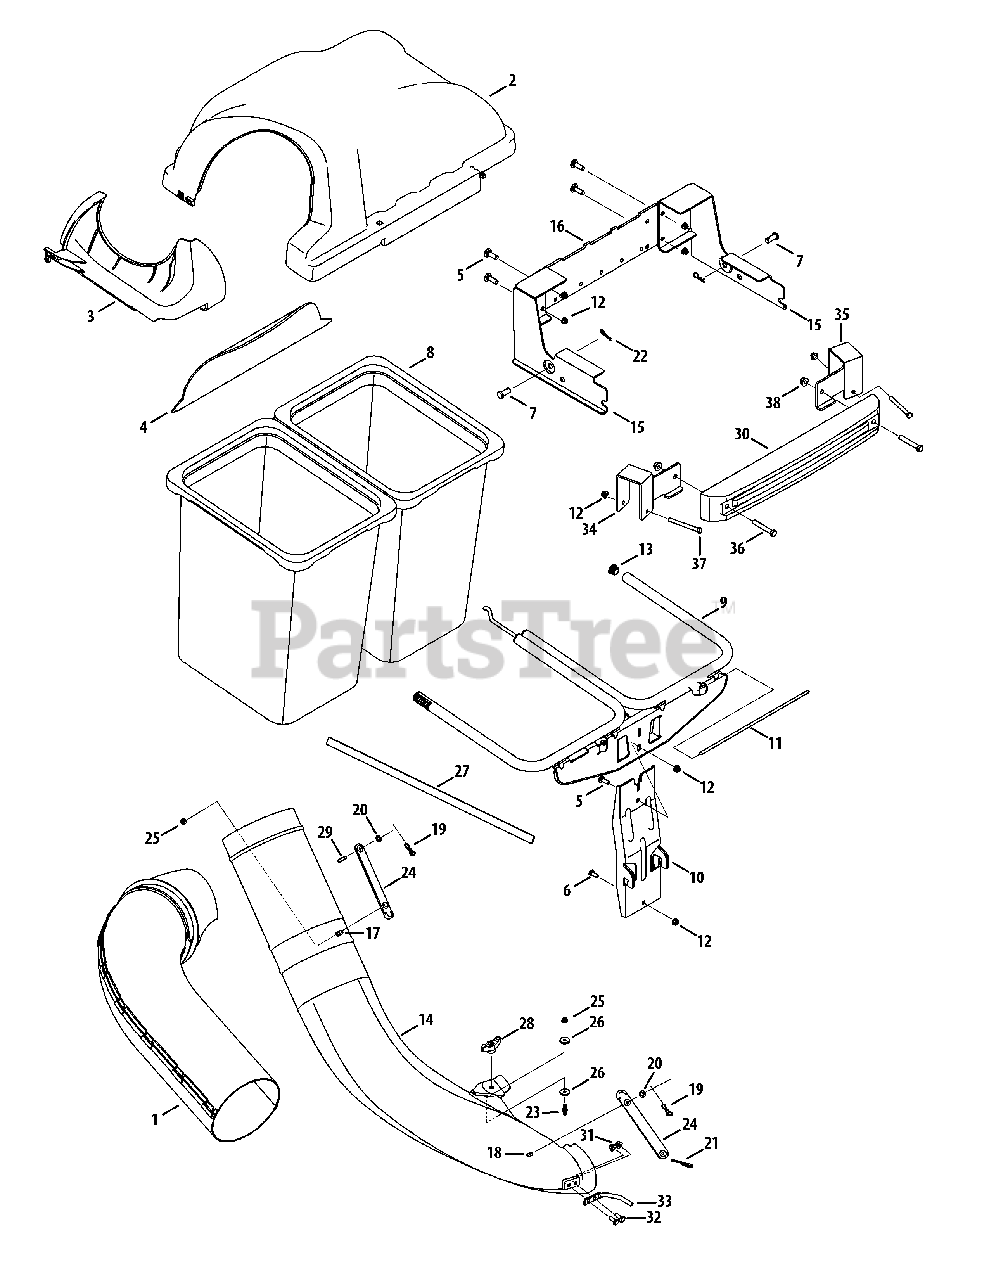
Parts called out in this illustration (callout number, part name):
1	Upper Chute Assembly
2	Twin Bagger Cover Assembly
3	Upper Chute Support
4	Bagger Cover Screen
5	Carriage Screw, 5/16-18 x 1.00"
6	Hex Head Screw, 5/16-18 x 1.00"
7	Clevis Pin, .50" Dia. x 1.18
8	Grass-bag Assembly
9	Twin Bag Support Assembly
10	Vertical Support Bracket
11	Cover Hinge Pin
12	Flange Lock Nut, 5/16-18
14	Chute, Lower
15	RZT Hitch Bracket Kit
16	Universal Cross Bracket
17	Grass-catcher Pin
18	Clevis Pin 5/16 x 3/4
19	Bow-Tie Cotter Pin
20	Flat Washer, .344 x .62 x .033
21	Torsion Spring Hook
22	Cotter Pin, .080 x 1.5625 Internal
23	Grass-catcher Pin
24	Chute Strap
25	Flange Lock Nut, 1/4-20
26	Flat Washer
27	Foam Strip
28	Wing Knob,
29	Pin, .25 Dia. x .9375 Lg.
30	Weight Bar, Bagger
32	Screw 1/4-20 x .62
33	Chute Rod, Lower
34	Right Mounting Bracket
35	Left Mounting Bracket
36	Hex Head Screw, 3/8-16 x 2.50
37	Hex Head Screw, 5/16-18 x 3-1/4
38	Flange Lock Nut, 3/8-16
